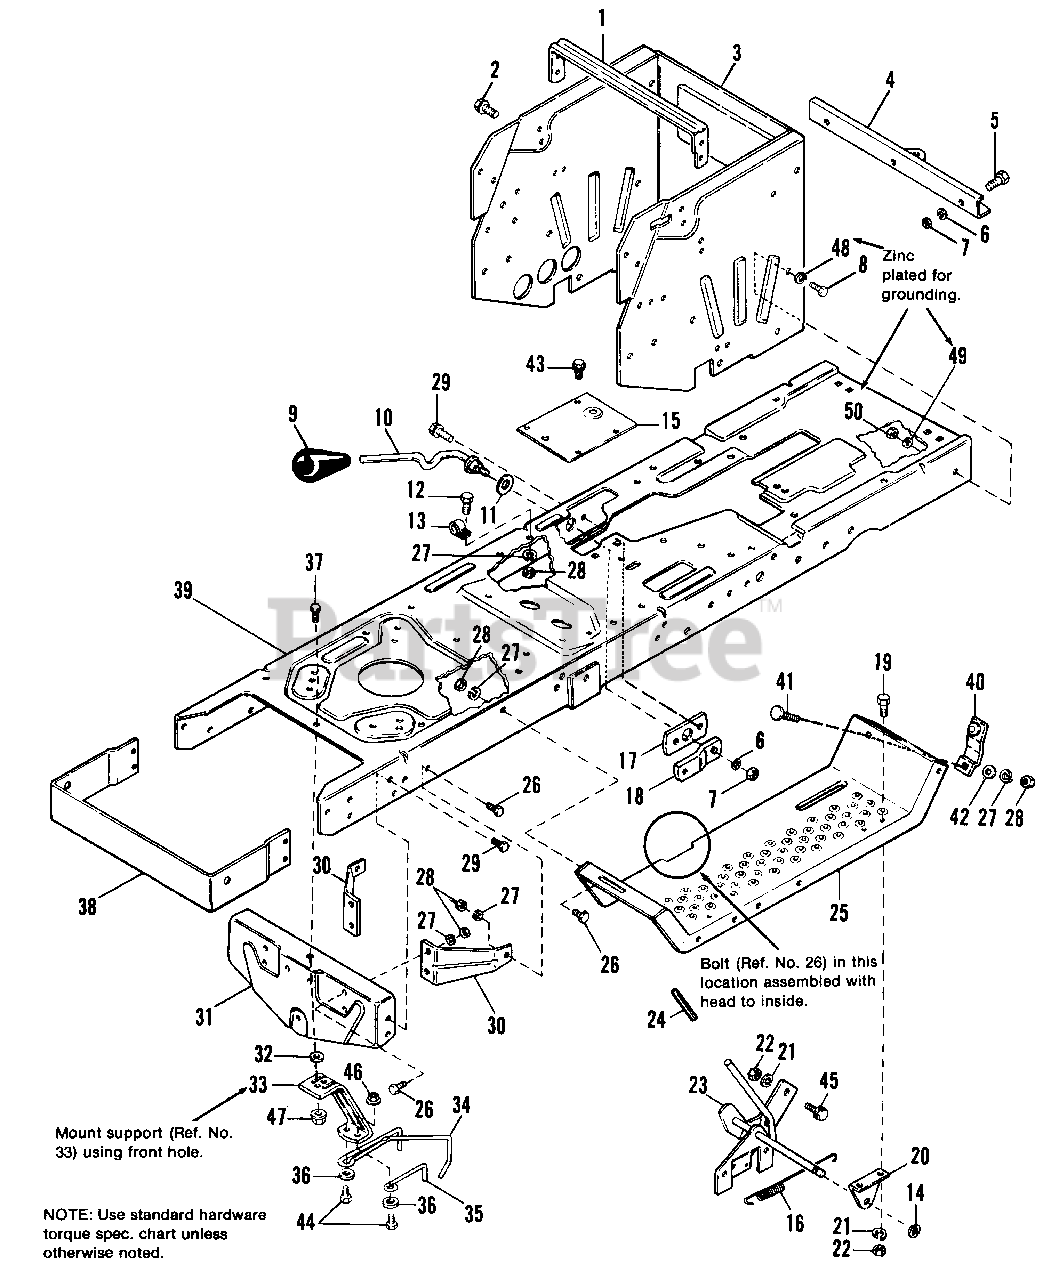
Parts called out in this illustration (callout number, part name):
1	BRACE, Seat
2	SCREW, Taptite, 5/16-18 x 1/2
3	SUPPORT, Axle Wrapper
4	BAR, Draw
5	CAPSCREW, Hex, 3/8-16 x 1
6	LOCKWASHER, 3/8
7	NUT, Hex, 3/8-16
8	CAPSCREW, Hex, 3/8-16 x 3/4
9	GRIP, Handle
10	HANDLE, Lift
12	CAPSCREW, Hex, 5/16-18 x 1-1/4
14	RING, Retaining
15	PLATE, Adaptor
16	SPRING, Extension
17	BAR, Support
18	ARM, Support
19	CAPSCREW, Hex, 1/4-20 x 5/8
20	SUPPORT, Clutch
21	LOCKWASHER, 1/4
22	NUT, Hex, 1/4-20
23	LEVER ASSY., Clutch, PTO
24	GRIP, Handle
26	CAPSCREW, Hex, 5/16-18 x 3/4
27	LOCKWASHER, 5/16 (Qty. 18 on 8 HP)
28	NUT, Hex, 5/16-18 (Qty. 18 on 8 HP)
29	SCREW, Taptite, 5/16-18 x 3/4
30	BRACE, Axle Support
31	SUPPORT, Axle
32	WASHER, Plain, 11/32-1 x 10 Ga.
36	WASHER, 1/4
37	CAPSCREW, Hex Hd., 5/16-18 x 1
40	LATCH ASSY.
41	CARRIAGE BOLT, 5/16-18 x 3/4
42	WASHER, Plain, 5/16
43	SCREW, Taptite, 1/4-20 x 1/2
44	CAPSCREW, Hex, 5/16-18 x 7/8
45	SCREW, Taptite, 1/4-20 x 5/8
46	LOCKNUT, Hex, Flange, 5/16-18
47	LOCKNUT, Flange Whiz, 5/16-18
48	LOCKWASHER, 3/8
49	LOCKWASHER, 3/8, Zinc Pltd.
50	NUT, 3/8, Zinc Pltd.
